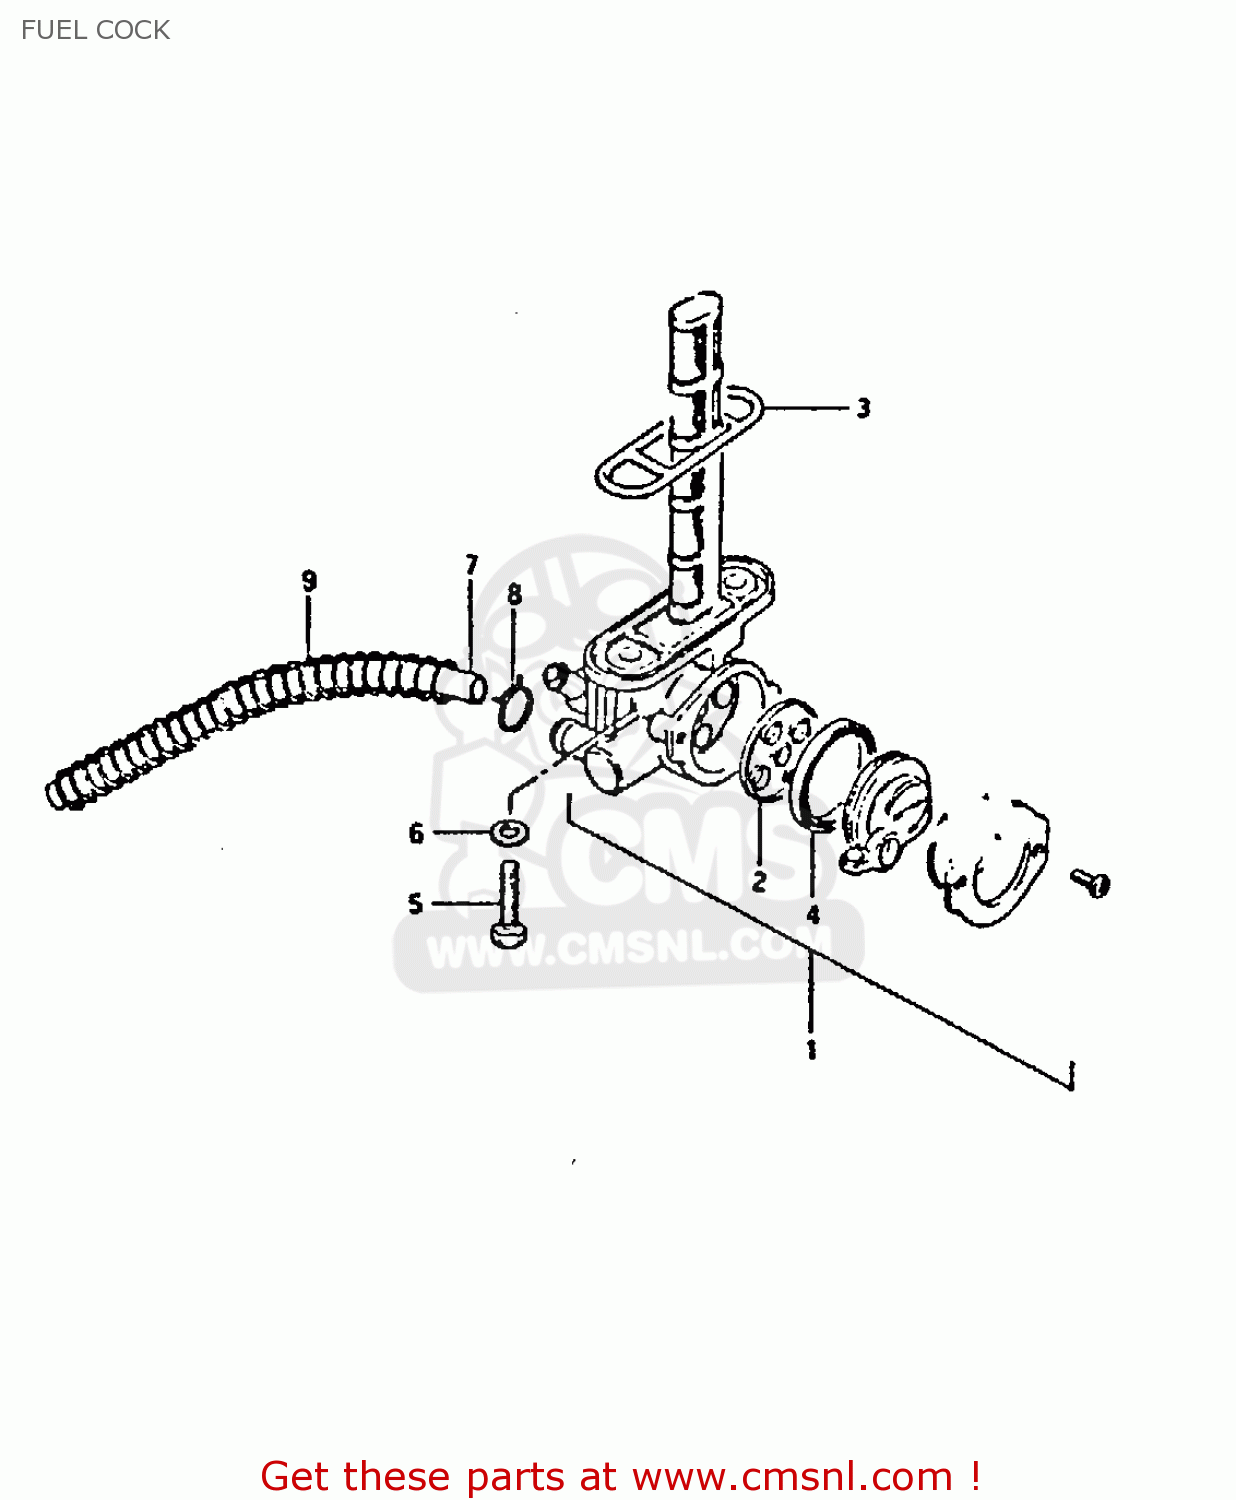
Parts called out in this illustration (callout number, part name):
1	COCK ASSY,FUEL
2	GASKET (NAS)
3	GASKET, FUEL COCK (NAS)
4	V SEAL,FUEL COCK
5	SCREW
6	GASKET
7	HOSE
8	CLIP
9	SPRING
